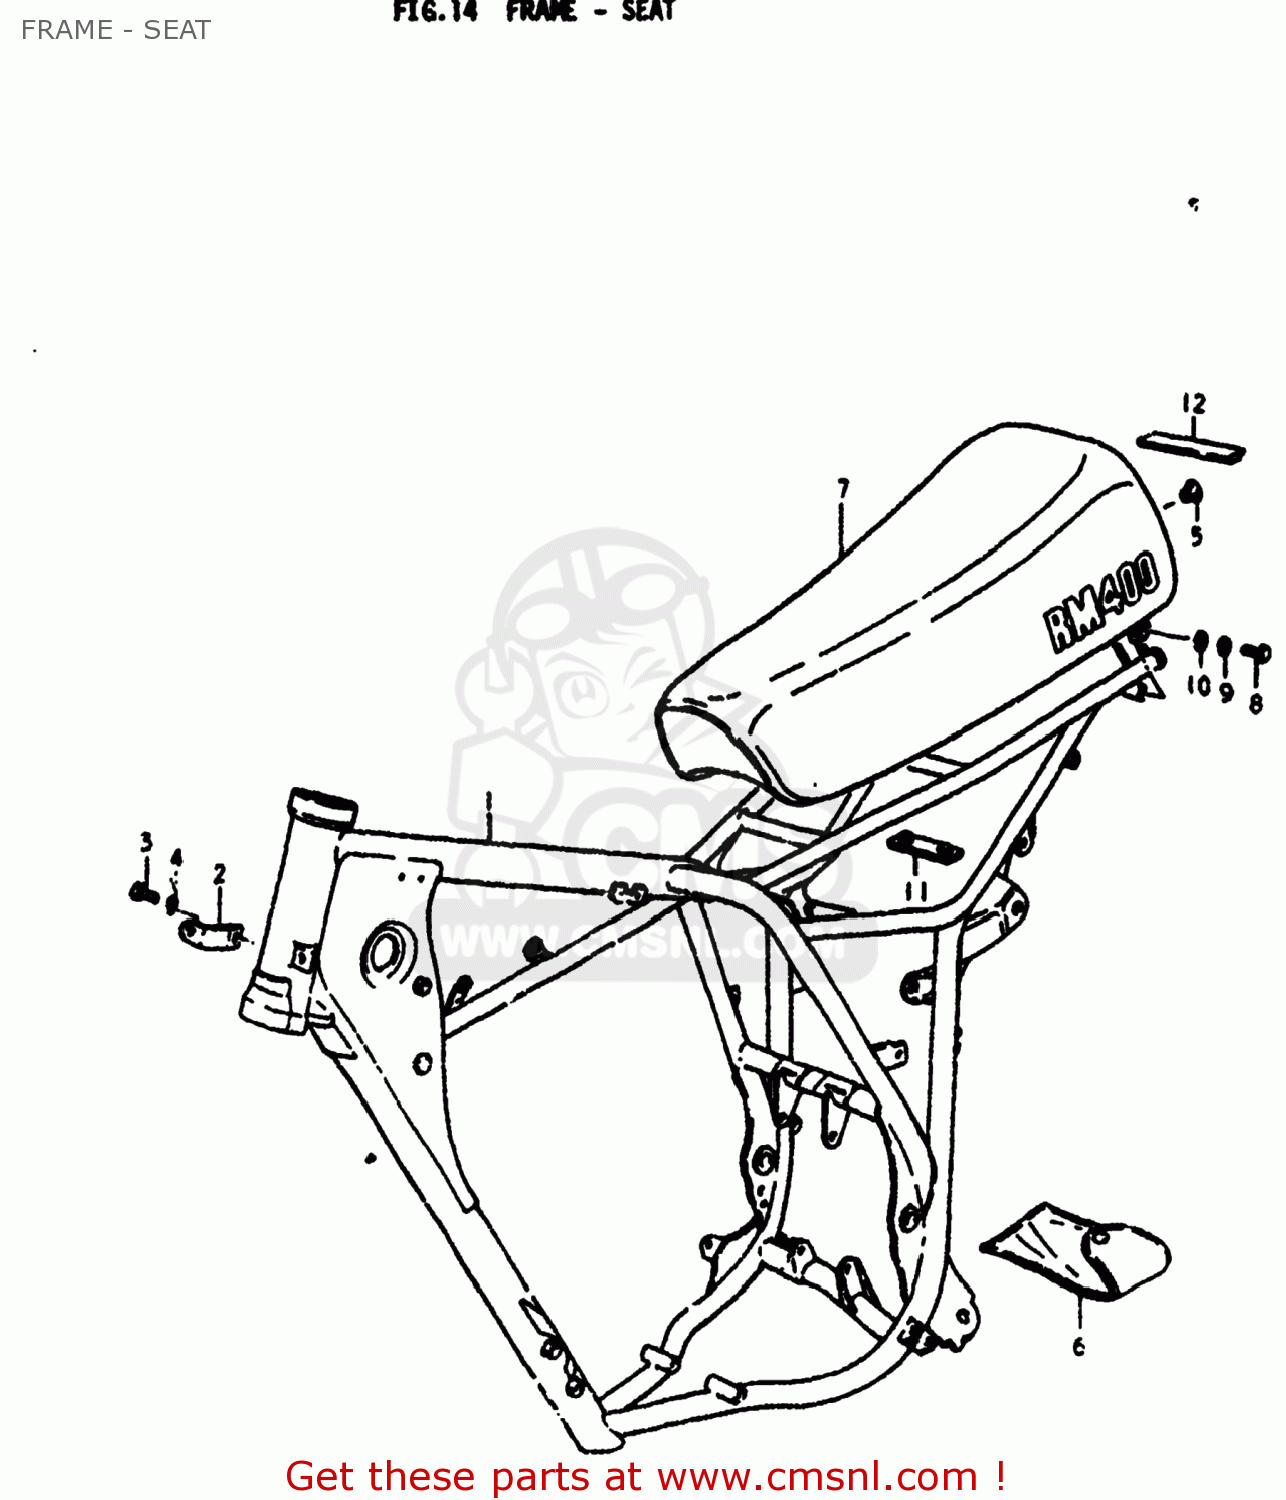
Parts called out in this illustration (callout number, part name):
1	FRAME
2	PLATE,ENGINE MOUNTING
3	BOLT
4	LOCK WASHER
5	CAP(OD:17)
6	TOOL SET
7	SEAT ASSEMBLY
8	BOLT
9	LOCK WASHER
10	WASHER
11	CUSHION
12	CUSHION,FRAME
